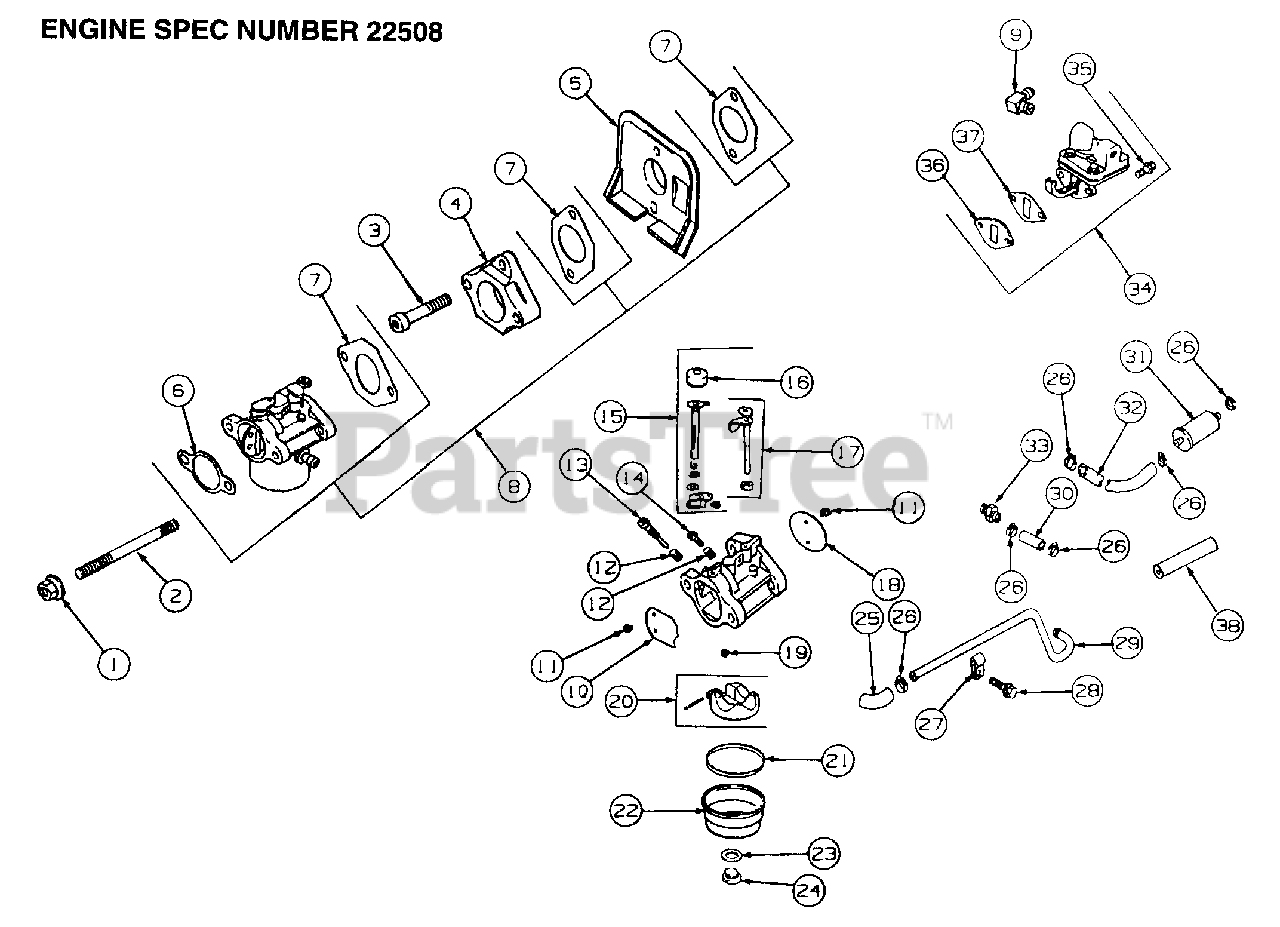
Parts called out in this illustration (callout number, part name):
1	Nut, Hex Flange, M6 x 1.0
2	Stud, Carburetor, M6 x 1.0 x 116
3	Screw, Socket Cap, M6 x 1.0 x 35
4	Adapter, Carburetor
5	Deflector, Heat
6	Gasket, Air Filter
7	Gasket, Carburetor
8	Kit, Carburetor w/Gskts
9	Connector, Hose, 90°.
10	Plate, Choke
11	Screw, Choke & Throttle Plate
12	Spring, Idle Fuel & Speed Adj
13	Needle, Idle Fuel Adj
14	Screw, Idle Speed Adj
15	Kit, Choke Shaft Repair
16	Cap, Choke Lever
17	Shaft, Throttle w/Seal
18	Plate, Throttle
21	Gasket, Bowl
23	Gasket, Bowl Retaining Screw
24	Screw, Bowl Retainer
25	Line, 90° Fuel
26	Clamp, Fuel Line
28	Screw, Hex Flange, M5 x 0.8 x 10
29	Line, Metal Fuel
30	Line, Fuel, 1-1/4"
31	Filter, Fuel
32	Line, Fuel, 5"
33	Connector, Straight Hose
34	Kit, Fuel Pump
35	Screw, Hex Flange, M6 x 1 x 20
36	Spacer, Fuel Pump
37	Gasket, Fuel Pump
38	Insulation, Fuel Line
